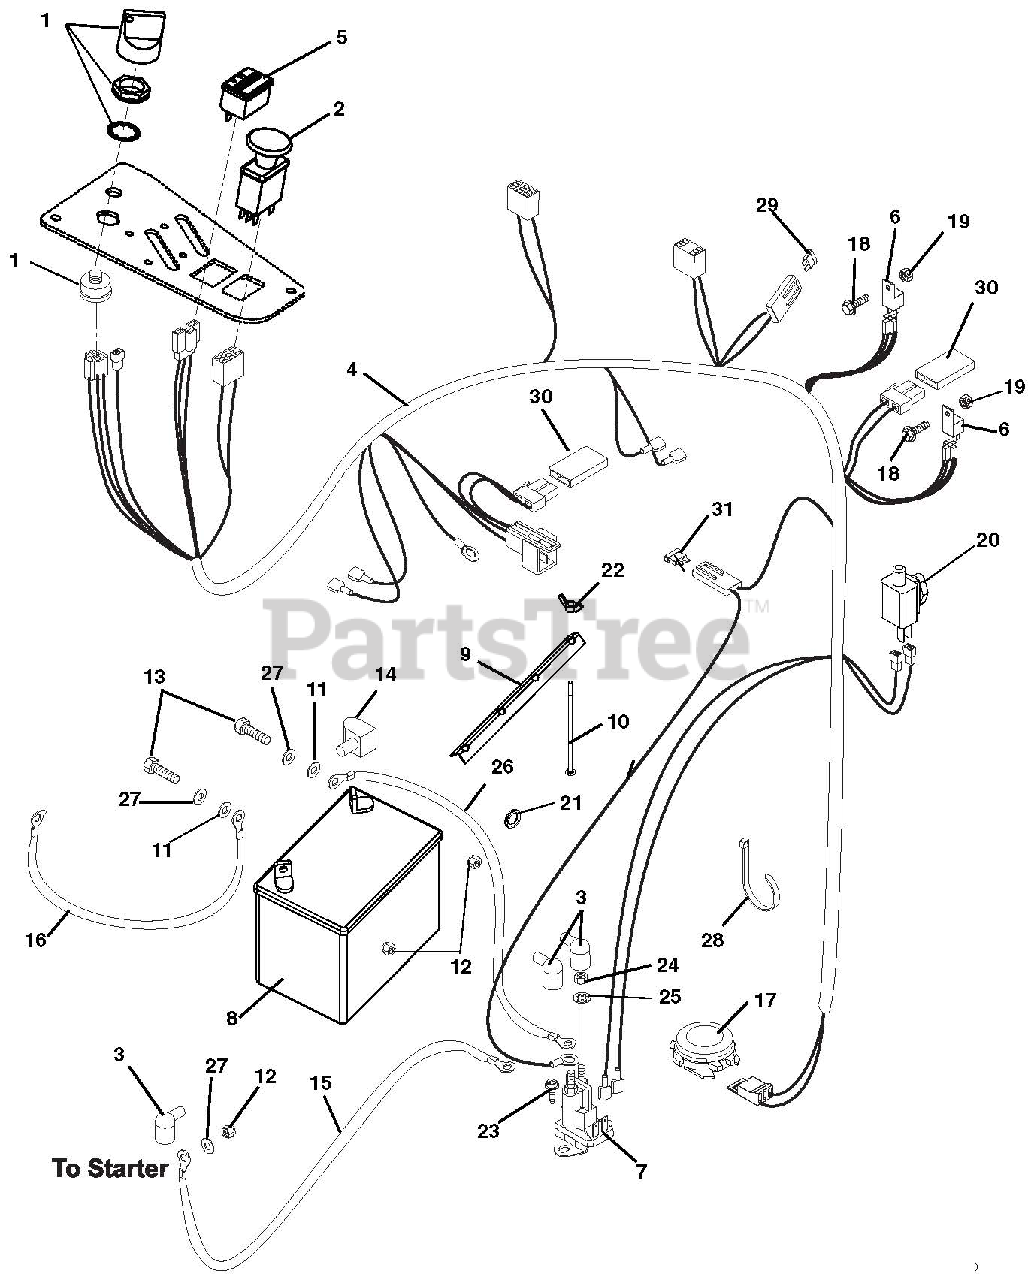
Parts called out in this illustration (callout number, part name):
1	Key Switch
2	Switch, Clutch
3	Boot, Eyelet Terminal
4	Harness- CZ Remote SOL.
5	Hour Meter – Digital
6	Relay, Sealed W/Diode
7	Solenoid
9	Hold Down
10	Bolt, Round Head Square Neck .25-20 x 7.50
11	Washer, Flat Steel .281 x .620 x .065
12	Nut, Hex .25-20
13	Bolt, Hex .25-20 x .75 Grade 5
14	Insulator
15	Cable, Positive Battery 9.00"
16	Cable, Negative Battery
17	Switch, Seat
18	Screw, Machine 10-24 x .50 Hex Washer Head
19	Nut, Locking Nylon 10-24 With Insert
20	Switch, Single Pole (N.O.)
21	Grommet, 2.12"ID .12"Groove Width, 2.50"Groove Diameter
22	Nut, Locking Wing .25-20
23	Screw, Tapping .25-20 x .50 Hex Washer Head
24	Nut, Jam .31-24
25	Washer, Locking .31 x .078 Regular
26	Cable, Starter
27	Washer, Lock .25 x .062
28	Tie, Cable LG 5.50
29	Fuse 20AMP
30	Diode, Connector Shell
31	Fuse-25 AMP
